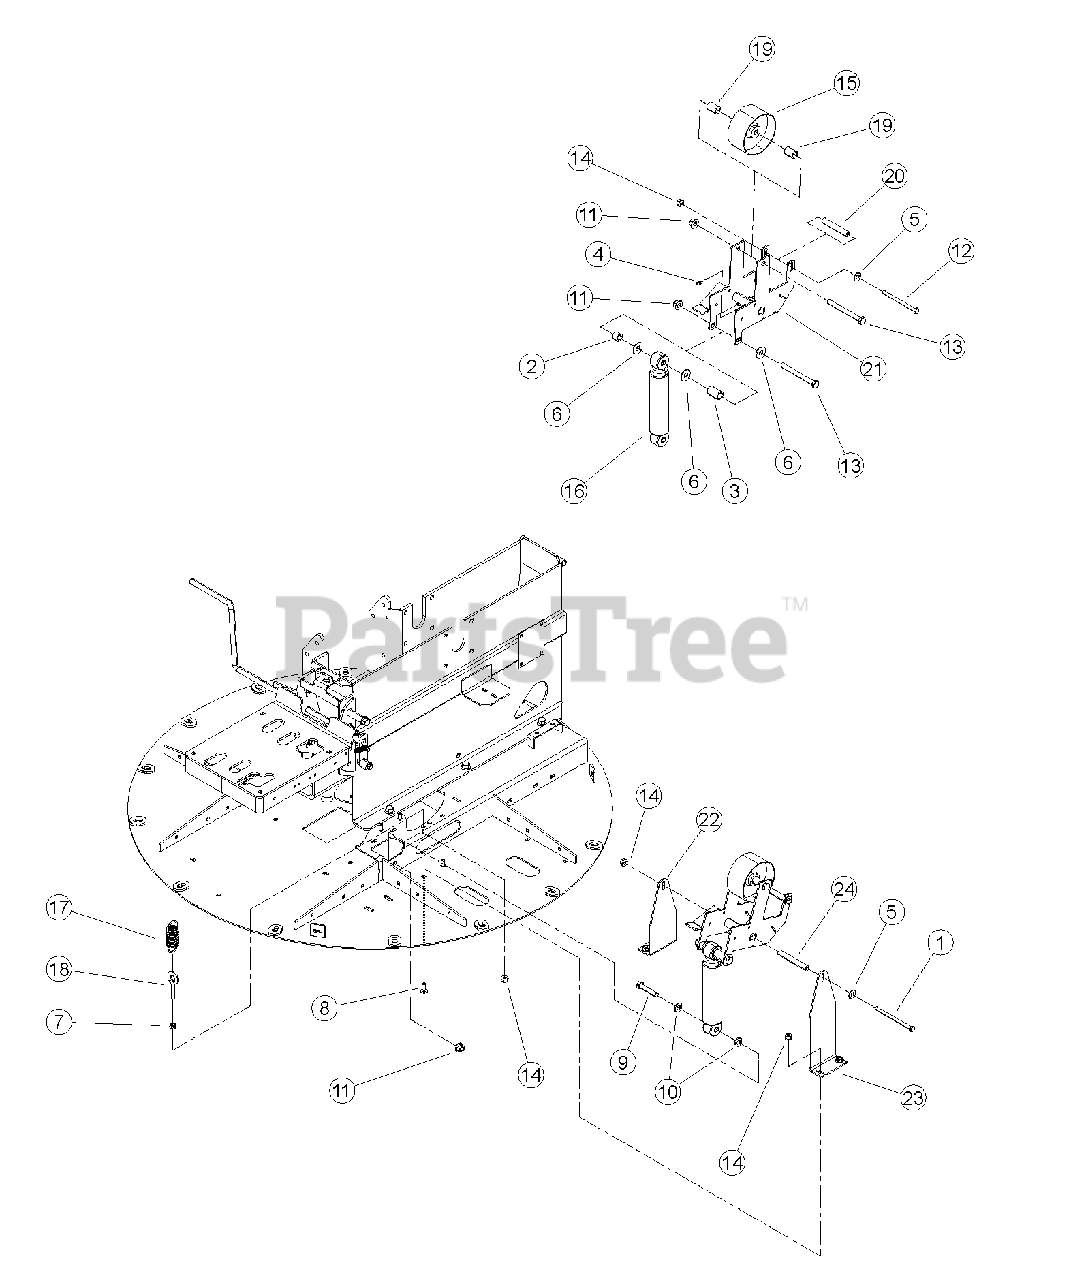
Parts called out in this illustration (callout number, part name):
1	BOLT, 3/8 X 5-1/2 HEX GR5 ZP
2	SPACER, .875 X .562 X .62 STL
3	SPACER, 1.00 X .688 X 1.50 STL
4	FITTING, 1/4 SELF-TAP GREASE
5	WASHER, 3/8" FLAT ZP
6	WASHER, 1/2" FLAT ZP
7	NUT, 3/8" SERRATED FLANGE NC ZP
8	BOLT, 3/8 X 1" GR5 CRG NC ZP
9	BOLT, 1/2 X 2-1/2 GR5 HEX CAP ZP
10	WASHER, 1/2" SAE FLAT ZP
11	NUT, 1/2-13 NYLOCK FLANGE
12	BOLT, 3/8 X 5" GR5 HEX CPS ZP
13	BOLT, 1/2 X 5" GR5 HHCS NC ZP
14	NUT, 3/8-16 NYLOCK FLANGE
15	PULLEY, IDLER 5 X 2.50"
16	ABSORBER, IDLER SHOCK
17	SPRING, 1.25OD X 3.50LG X .148WD
18	EYE BOLT G-2, 3/8 X 2" ZP
19	SPACER, .875 X 1.25
20	SPACER, 5/8 OD X 11 GA X 3.80
21	WELDMENT, BELT IDLER
22	ANGLE, IDLER BRACKET
23	ANGLE, IDLER BRACKET
24	SPACER, 5/8 OD X 11 GA X 4.30
